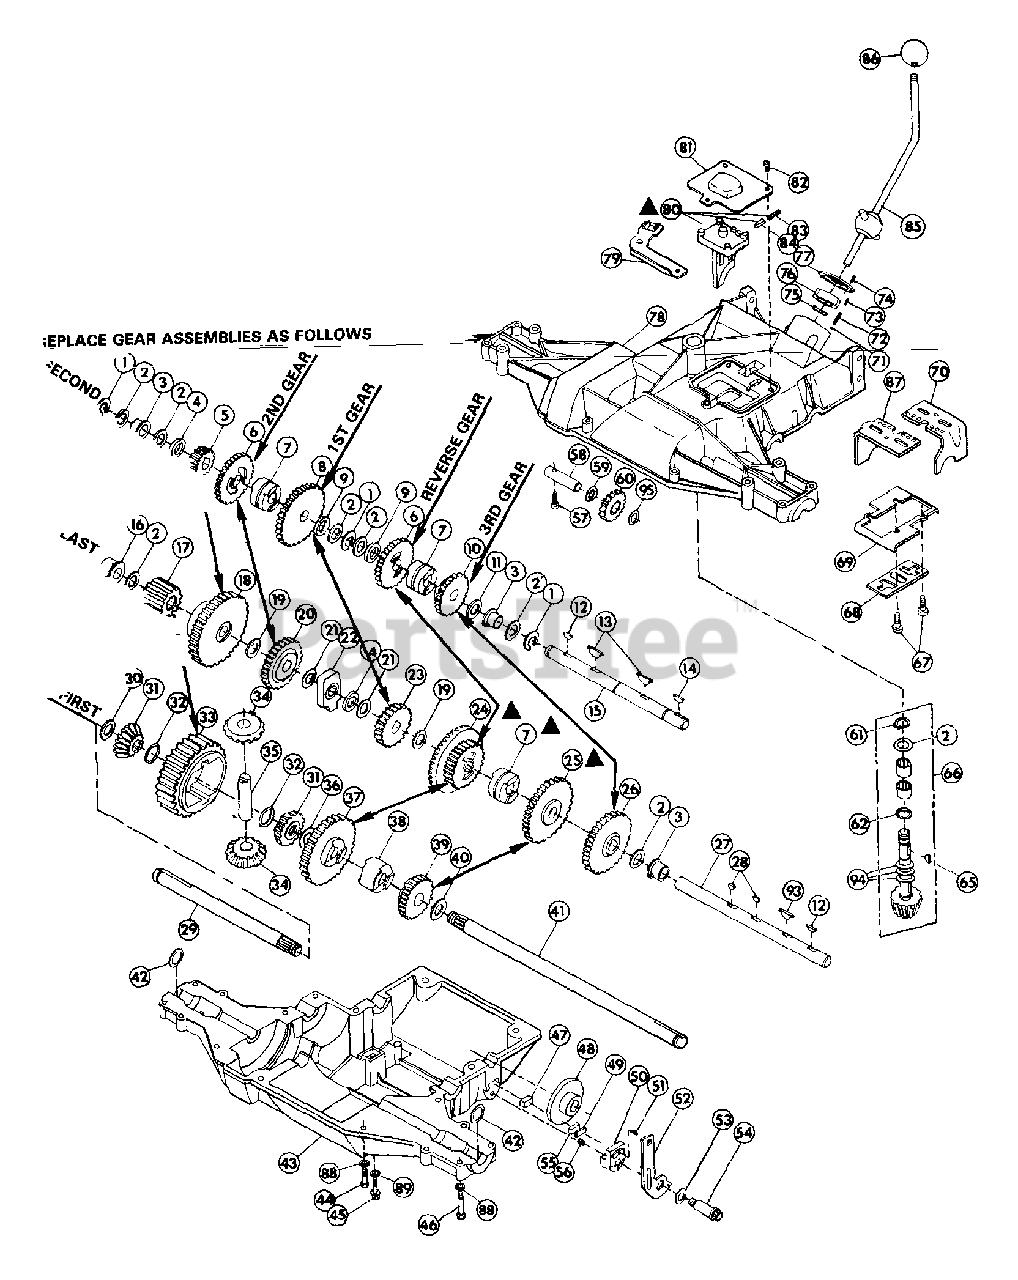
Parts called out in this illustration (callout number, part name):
1	RG-RTNG-EXT .625X.042
2	SHIM KIT
3	FLANGE BEARING
4	SPACER .630X1.000X.110
5	SPUR GEAR 13T
6	SPUR GEAR 25T
7	CLUTCH COLLAR
8	SPUR GEAR 30T
9	SPACER .633X1.00X.260
10	SPUR GEAR 20T
11	WASHER
12	KEY-WDRF .125X.500X.203 SAE 3
13	KEY-FTHR .188X1X.297
14	KEY-WDRF .188X.625X.25 SAE 61
15	INTERMEDIATE SHAFT
16	FLANGE BEARING
17	GEAR ASSY 12T
18	SPUR GEAR 37T
19	WASHER
20	SPUR GEAR 25T
22	SHAFT SUPPORT ASSY
23	SPUR GEAR 20T
24	BEVEL GEAR ASSY
25	SPUR GEAR 33T
26	SPUR GEAR 30T
27	DRIVE SHAFT
28	KEY-WDRF FOOTE #3311
29	L H AXLE
30	SHIM KIT
31	SPLINED MITER GEAR 15T
32	RG-RTNG-EXT .625X.035
33	SPUR GEAR 32T
34	MITER GEAR 15T
35	CROSS SHAFT
36	WSHR-HDND-THRST .758X1.23X.031
37	SPUR GEAR 35T
38	GEAR LOCK
39	SPUR GEAR 22T
40	WSHR-FL-STL .760X1.250X.060 PL
41	R H AXLE
42	SEAL J.B.FOOTE #5130
43	LOWER HOUSING
44	BLT-HEX .25-20X1.00 GR2
45	SCR-MCH 12-24X.62 HEXWH
46	BLT-HEX .25-20X1.50 PL GR5
47	BRAKE JAW FRICTION PUCK
48	BRAKE DISC
49	SPACER - FLAT .045 THICK
50	BRAKE JAW ASSY
51	SCR-SET 8-32 FOOTE 1606
52	ACTUATING LEVER ASSY
53	SHIM KIT
54	SHOULDER BOLT
55	FRICTION PAD
56	SG-COMP J.B. FOOTE
57	SCR-MCH 10-24X1.00 HEX PL
58	IDLER SHAFT
59	WSHR-FL-STL .505X1.000X.020
60	IDLER GEAR ASSY
61	RG-RTNG-EXT .625X.035
62	O-RING .612X.805X.102
65	KEY-WDRF .188X.75X.313 SAE 9
66	INPUT SHAFT ASSY KIT
67	BLT-HEX .25-28X.75 PL GR5
68	LOCK-OUT PLATE
69	FORK PLATE SUPPORT
70	SHIFTER FORK
71	DETENT BALL
72	SG-COMP ??X??X?? FOOTE
73	SCR-SET .25-20X.38 SKHCUP OH
74	SCR-MCH 10-24X.50 SLTR PL
75	WAVE WASHER .760X1.062X.105FH
76	NYLON INSERT
77	NYLON COVER
78	UPPER HOUSING
79	HI-LO SHIFT LEVER
80	SELECTOR FORK KIT
81	HI-LO COVER PLATE
82	SCR-MCH 8-32X.50 SLTR PL
83	SG-COMP .035X.186X.702
84	DETENT PIN
85	SHIFT LEVER ASSY
86	SHIFT BALL
87	SHIFTER FORK
88	WSHR-LK .250X.077 HVY PL
89	WSHR-LK-EXT 12X.025 PL
93	KEY-FTHR FOOTE #3068
94	SHIM KIT
95	WASHER .030 THK
95	WSHR-FL-STL .505X1.000X.020
